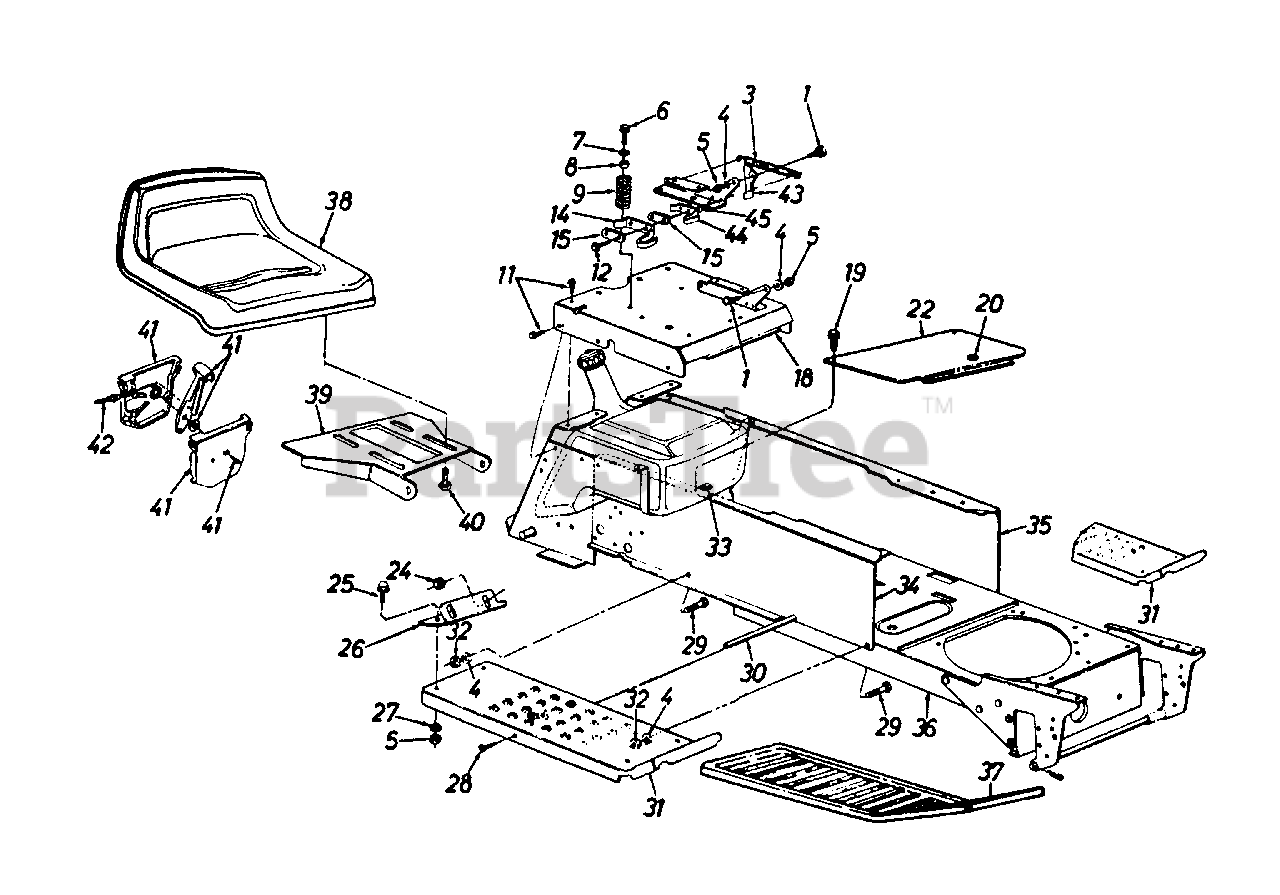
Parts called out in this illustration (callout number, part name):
1	Shld. Bolt .437" Dia. x .162"
3	Ext. Spring 5.31" Lg.
4	L-Wash. 5/16" I.D.
5	Hex Nut 5/16-18 Thd. (Gr. 5)
6	Hex Wash. Hd. Tap Scr. 5/16-18 x .7" Lg.
7	Fl-Wash. .344" I.D.
8	Bushing
9	Compression Spring
11	Hex Wash. Hd. AB-Tap Scr. 5/16 x .75" Lg.
12	Hex Wash. Hd. AB-Tap Scr.#8 x .5" Lg.
14	Spring Switch
15	Insulator Plate
18	Seat Plate
19	Truss Mach. B-Tap Scr.#10 x .5" Lg.
20	Snap Bushing
25	Hex Bolt 5/16-18 x .75" Lg.
28	Truss Mach. Scr. 5/16-18 x .75" Lg.
29	Rib Neck Bolt 5/16-24 x .75" Lg.
30	Running Board Rod
33	Speed Nut #10Z
38	Seat
40	Hex Tap Scr. 3/8-16 x .62" Lg.
41	Throttle Control Box Ass'y.
42	Throttle Control Wire 35" Lg.
43	Seat Lift Bracket
44	Seat Spring Switch
45	Insulator Boss Plate
